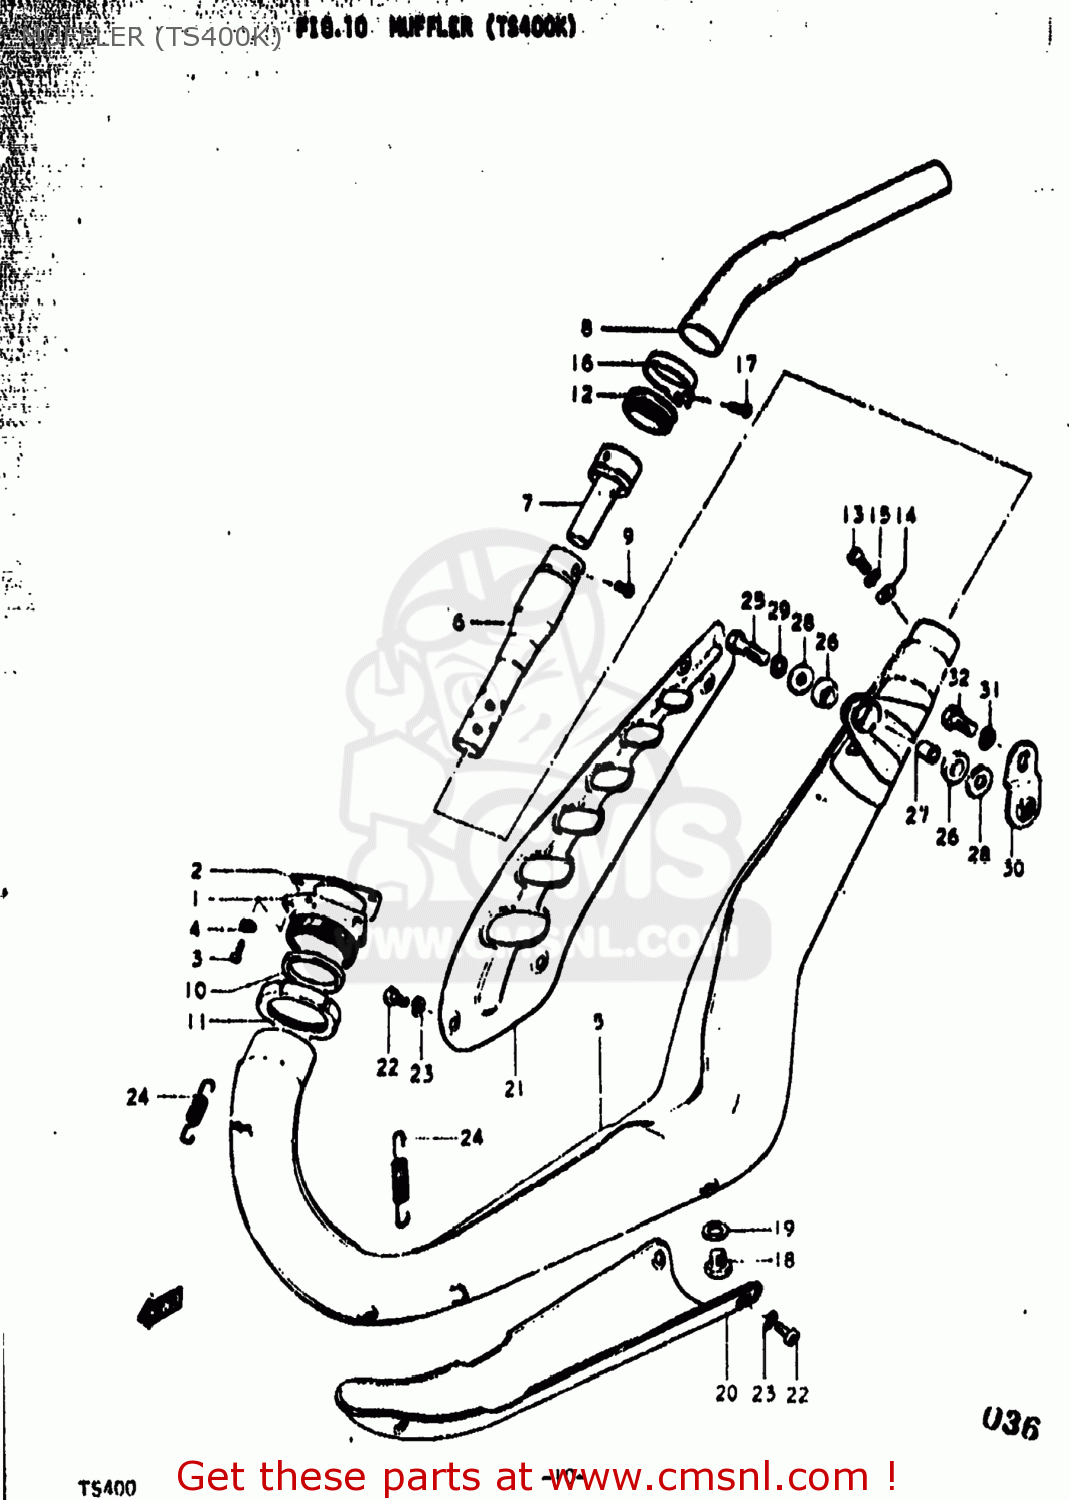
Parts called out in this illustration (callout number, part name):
1	FLANGE,EXHAUST PIPE
2	GASKET,EXHAUST PIPE (MCA)
3	SCREW
4	LOCK WASHER
5	MUFFLER ASSEMBLY
6	ARRESTER,SPARK
7	TUBE,MUFFLER CLEAN OUT
8	EXHAUST EXTENSION
9	SCREW
10	CLAMP,EXHAUST PIPE
11	HOLDER,EXHAUST PIPE CLAMP
12	GASKET,MUFFLER TAIL PIPE (NAS)
13	Screw
14	GASKET
15	LOCK WASHER
16	CLAMP
17	SCREW
18	PLUG
19	GASKET(10X14X3.6) (NAS)
20	COVER,MUFFLER
21	COVER,MUFFLER
22	SCREW
23	LOCK WASHER
24	SPRING
25	BOLT 8X40
26	CUSHION
27	SPACER (8.2X12.5X23.5)
28	WASHER (8.7X22X2)
29	LOCK WASHER
30	BRACE,MUFFLER
31	LOCK WASHER
32	BOLT
